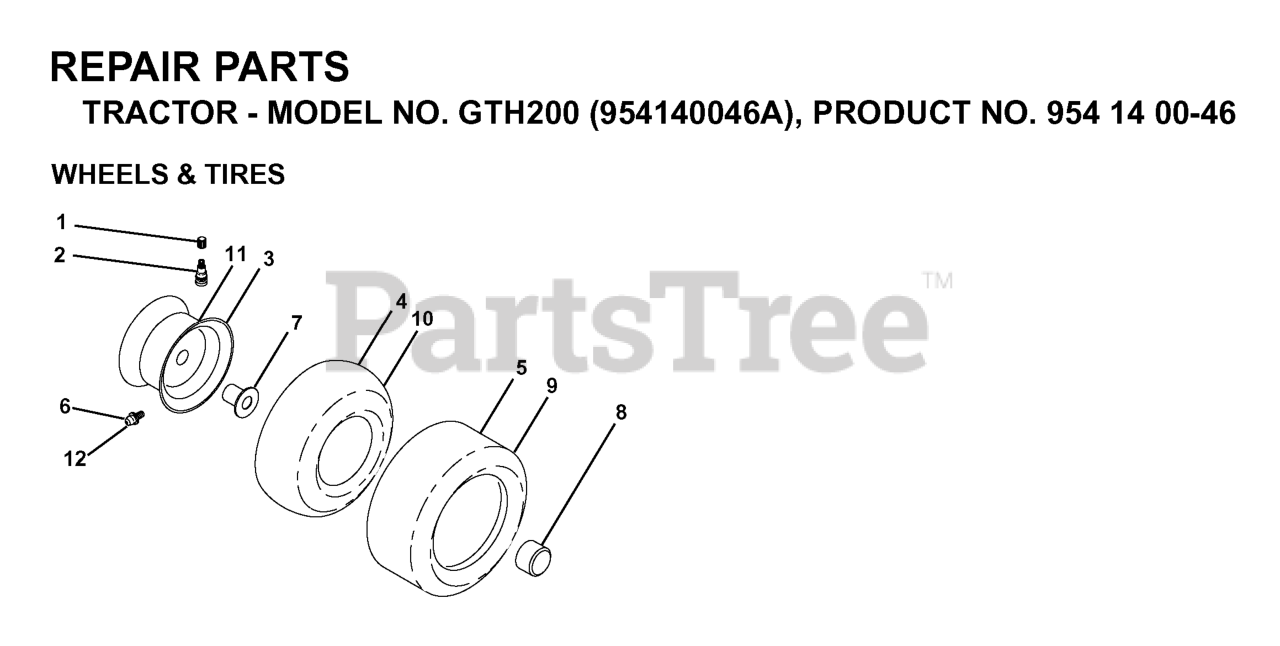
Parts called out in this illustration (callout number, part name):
2	VALVE STEM LT
3	RIM ASSEMBLY, FRONT
4	TUBE.16X6.5/7.5-8
5	TIRE HEAVY DUTY
6	ZERK FITTING M
7	BEARING T
8	CAP.HUB.FRONT.LT.BLACK
9	TIRE HEAVY DUTY
10	TUBE.23X9.5-12
11	RIM.ASM.12X7.REAR.SILVER
12	FITTING LT
